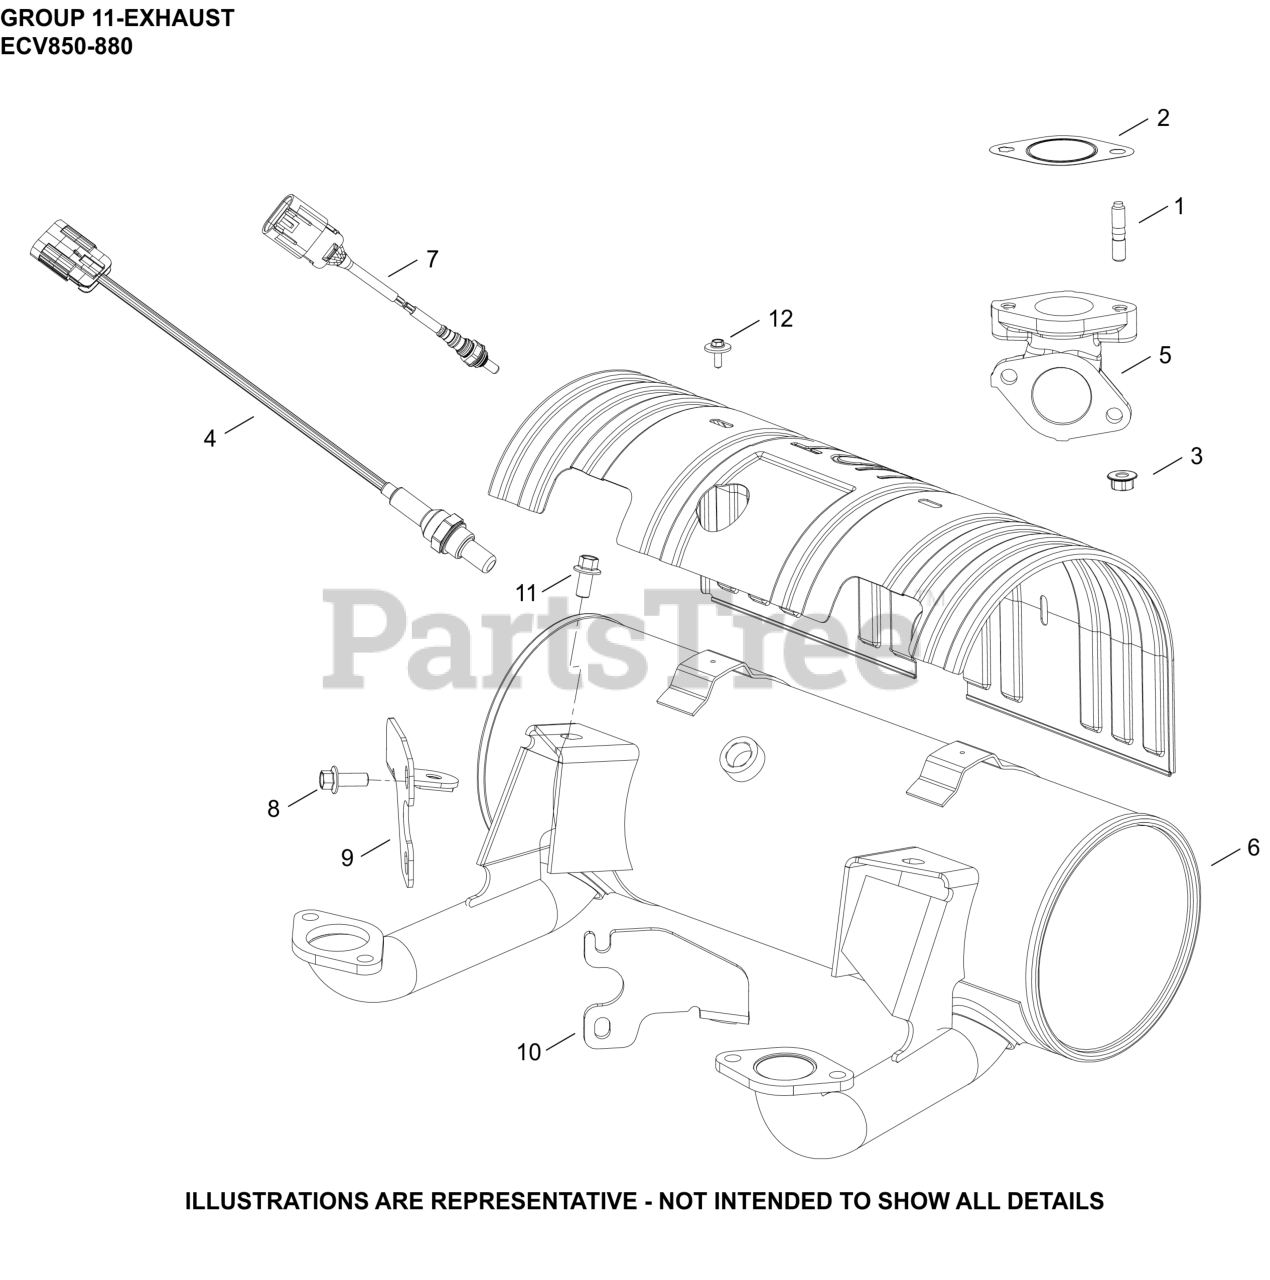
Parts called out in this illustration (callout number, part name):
1	STUD, METRIC EXHAUST
2	GASKET, EXHAUST MANIFOLD
3	NUT, HEX FLANGE LOCK (M8)
7	SENSOR, OXYGEN (M12 x 1.25 THREADS)
